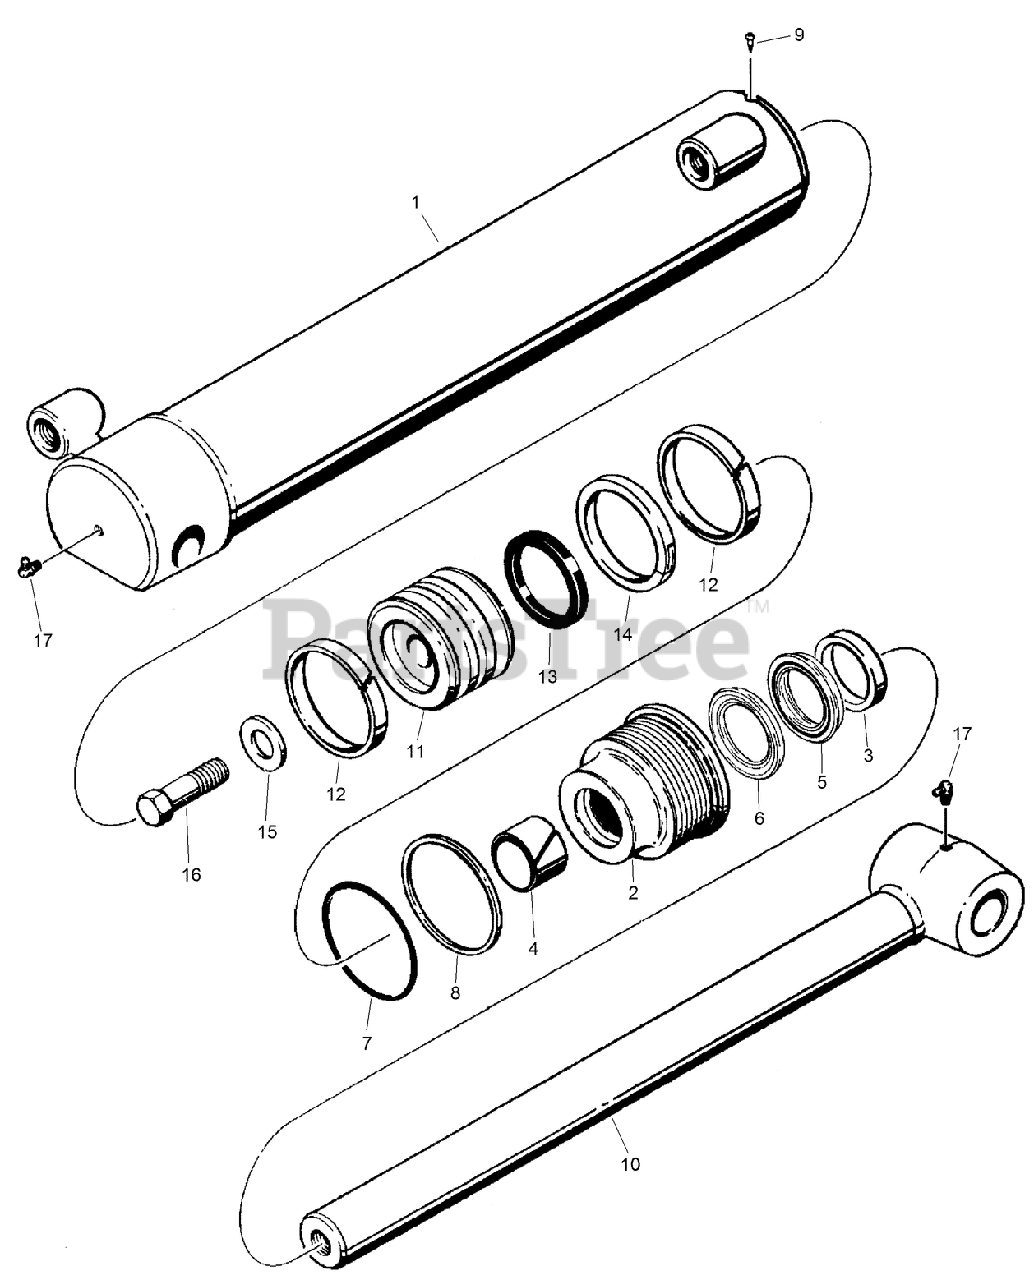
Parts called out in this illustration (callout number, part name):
1	TUBE-cylinder
2	GLAND-cylinder
3	WIPER-ROD
4	BEARING-ROD
5	SEAL-Rod, NSS, order 1543256C1 kit, see below
6	SEAL-Buffer, NSS, order 1543256C1 kit, see below
7	O-RING-3 ID x 1/8 inch wide, gland
8	RING-backup, gland O-ring
10	ROD-piston, 38 mm (1-1/2 inch) diameter
11	PISTON-cylinder
12	RING-WEAR
13	RING-LOADER
14	SEAL-Piston
15	WASHER-flat, special, hardened
16	BOLT-hex, 3/4 NF x 2-1/2 inch, grade 8
17	FITTING-grease, 90 degree, 1/8 PT x 27/32 inch
